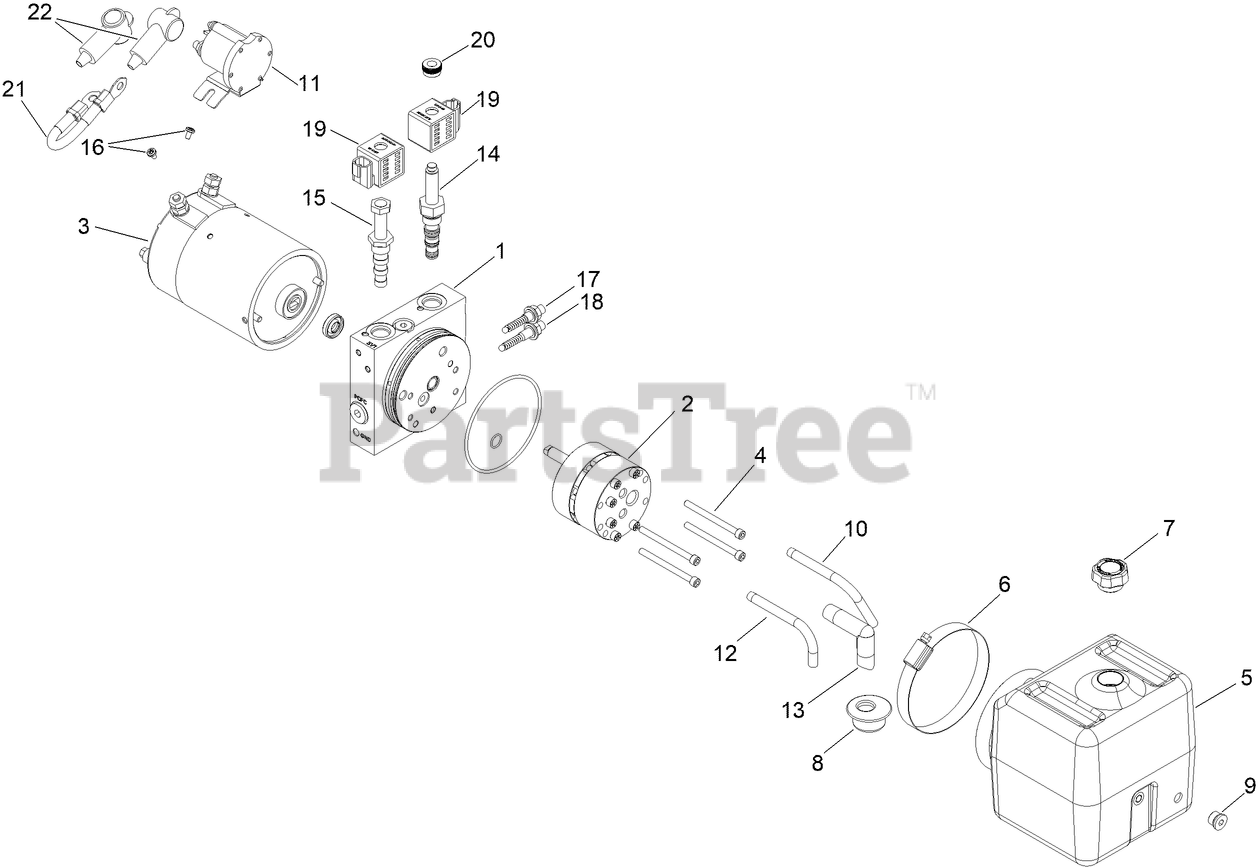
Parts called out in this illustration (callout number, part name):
1	BASE ASM,M3556,MOD,STD MTR/MT
2	P ASSY,QM MDLR,DC,BRGS BLD RSV
3	MOTOR-DC,36/48V,4.5IN,2 TERM,UL
4	RESERVOIR-PLASTIC,6.7X6.7X7.5,H/MT
5	SCREW-SHC,1/4-20 X 3.0,BLK OX
6	CLAMP-HOSE,WORM GEAR,RSV,M-SER
7	PLUG-RESERVOIR,BREATHER-FILLER
8	FILTER-SCREEN M-SERIES SUCT.
9	PLUG,SAE O-RING,9/16-18,HEX,SO
10	TUBE-RETURN,90DEG,1/8NPT,M301
11	SWITCH,SOL ACT MTR ST,48VLT
12	TUBE-RETURN,90DEG,1/8NPTF
13	TUBE-SUCTION,90 DGR,3/8NPT
14	CARTRIDGE,2W/2P W/ PO CHCK,NC
15	CARTRIDGE,4-W/2-P,#8,1/2"STEM
16	SCREW-PAN HD,TORX,10-32 X 5/16
17	VALVE ASM,BLUE,>1000 PSI,R/V
18	VALVE ASM,BLUE,>1000 PSI,LNG SCW,R/V
19	COIL,48VDC,#8,DEUTSCH,UL
20	NUT,VALVE,COIL,SIZE 8,KETA,TAL
21	CABLE-INSULATED W/LUGS 5IN,6GA,UL
22	BOOT-TERMINAL,#4 CABLE,INSULATED
